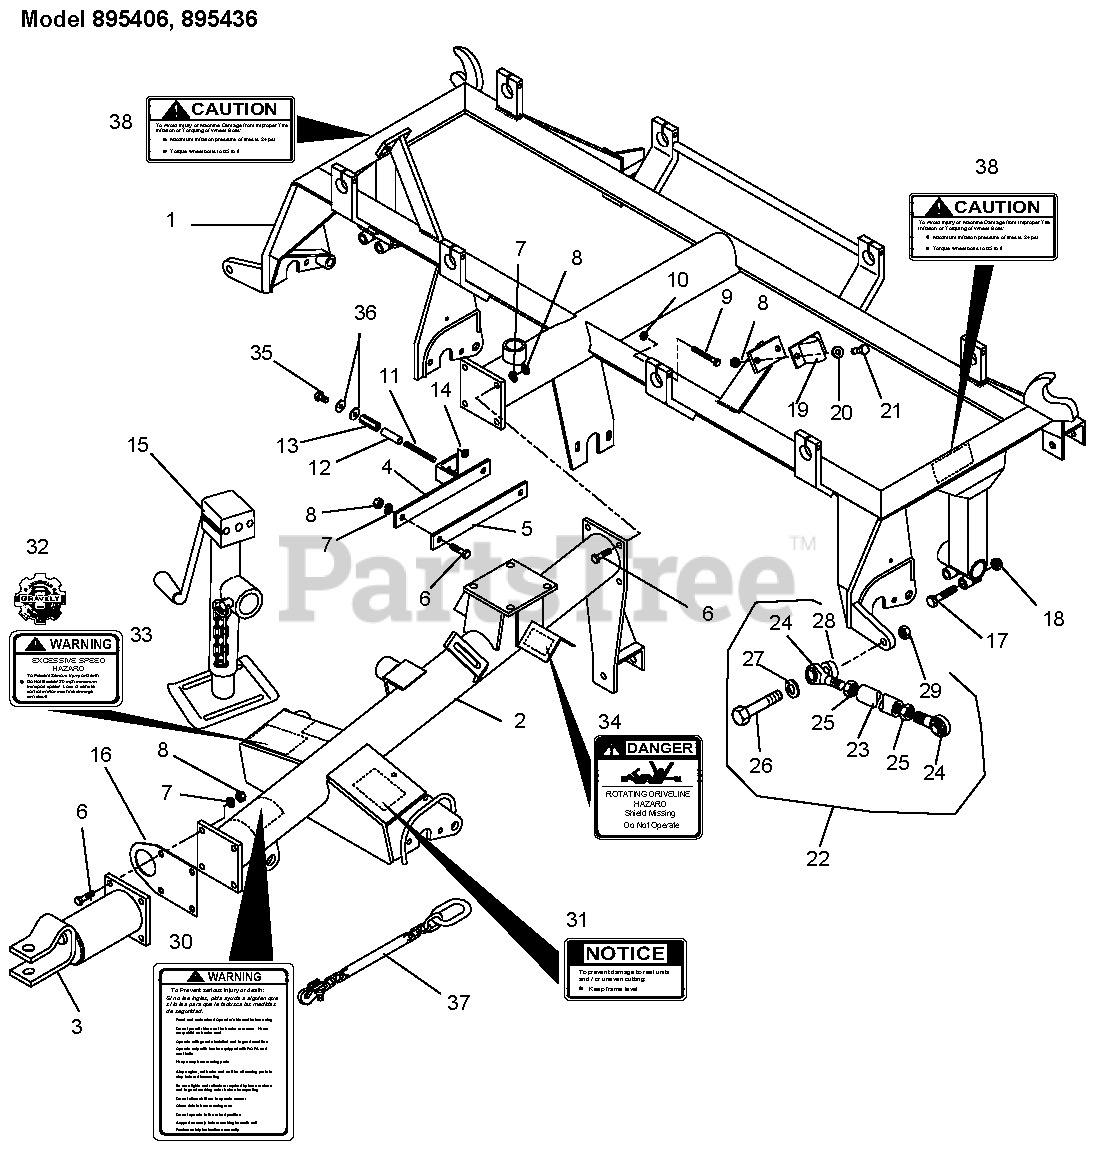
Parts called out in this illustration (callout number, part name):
1	Weldment, Mainframe
2	Tongue Assembly
3	Weldment, Clevis Hitch
4	Weldment, Tongue Brace
5	Brace, Tongue Left Hand
6	Cap Screw, Hex Head .50-13 x 1.5
7	Washer, Lock .50
8	Nut, Hex .50
9	Cap Screw, Hex Head .375-16 x 3
10	Nut, Hex .375-16 CP Nylock
11	Stud, Belt Guard
13	Nut, Hex Coupler .375-16
14	Nut, Jam .375-16
15	Jack, Screw 5000 lb.
16	Holder, Hydraulic Hose
17	Cap Screw, Hex Head .50-13 x 2.5
18	Nut, Hex .50-13 Nylock
19	Bumper, Rubber
20	Washer, Flat .50
21	Cap Screw, Hex Head .50-13 x 1
22	Tie Rod Assembly, Outer
23	Tie Rod, Outer
24	Rod End, .625 Bore, Right Hand Thread
25	Nut, Hex .625-18
26	Cap Screw, Hex Head .625-11 x 2.5
27	Washer, Lock .625
29	Nut, Hex .625-11
30	Decal, Warning
31	Decal, Notice
32	Decal, Gravely Heritage Small
33	Decal, Warning
34	Decal, Danger
35	Cap Screw, Hex Head .375-16 x .75
36	Washer, Flat .375
37	Chain, Safety Tow
38	Decal, Caution
